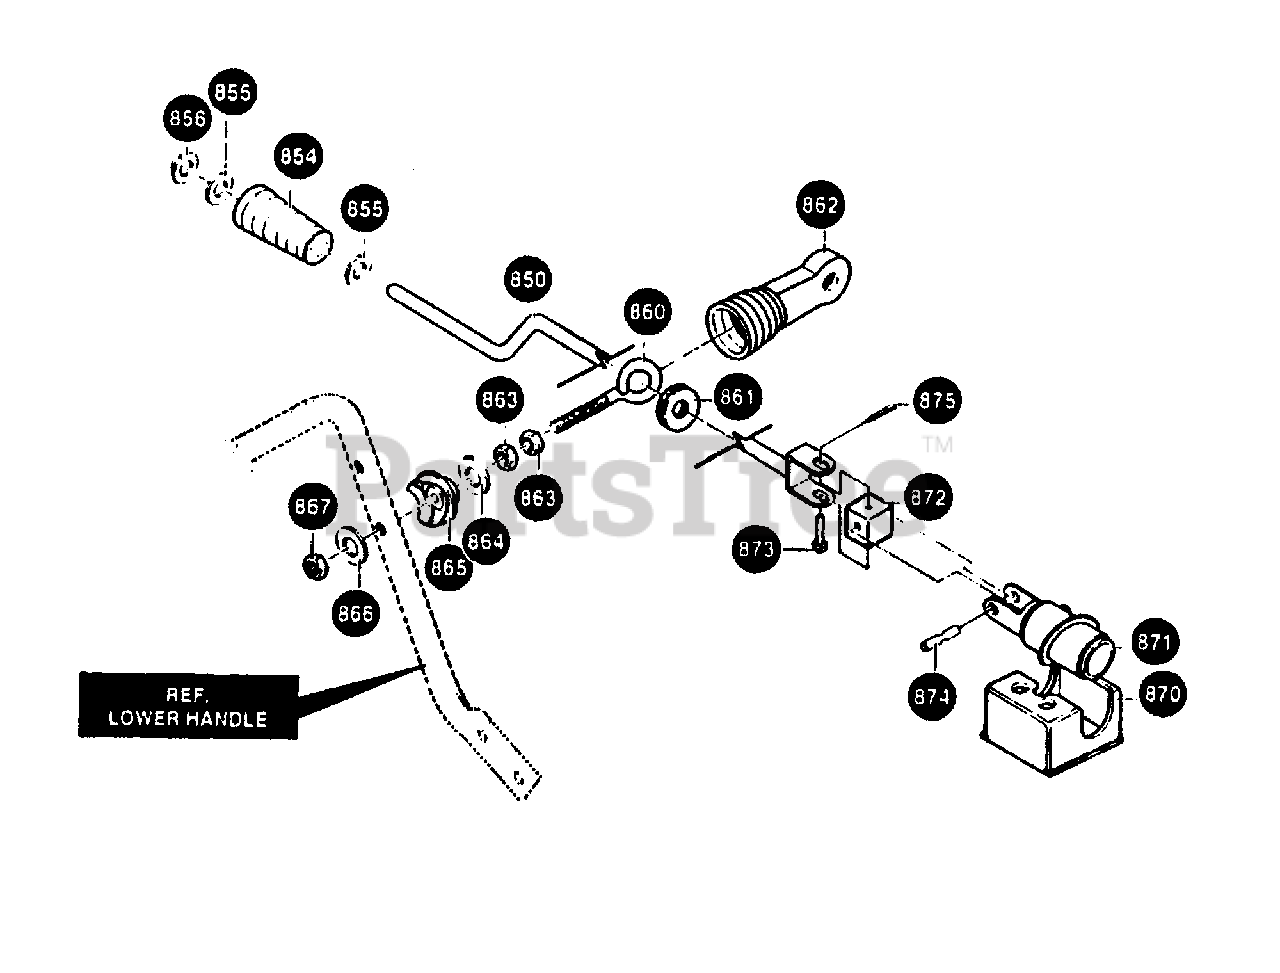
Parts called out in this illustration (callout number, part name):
850	CRANK, ASSY W/YOKE
854	HANDLE, CRANK
855	WASHER, FLAT
856	NUT, PUSH ON 3/8"
860	BOLT, EYE 6
861	GROMMET, EYE BOLT
862	BOOT, EYE BOLT
863	NUT, 3/8-16 HEXJAM
864	WASHER, FLAT .406X .81X.065
865	ADAPTER, BOOT
866	WASHER, FLAT .406X .81X.065
867	NUT, 3/8-16
870	BRACKET, WORM
871	WORM, GEAR CHUTE
872	BLOCK, UNIVERSAL
873	PIN, CLEVIS
874	PIN, UNIV JOINT
875	PIN, COTTER .06X .50
